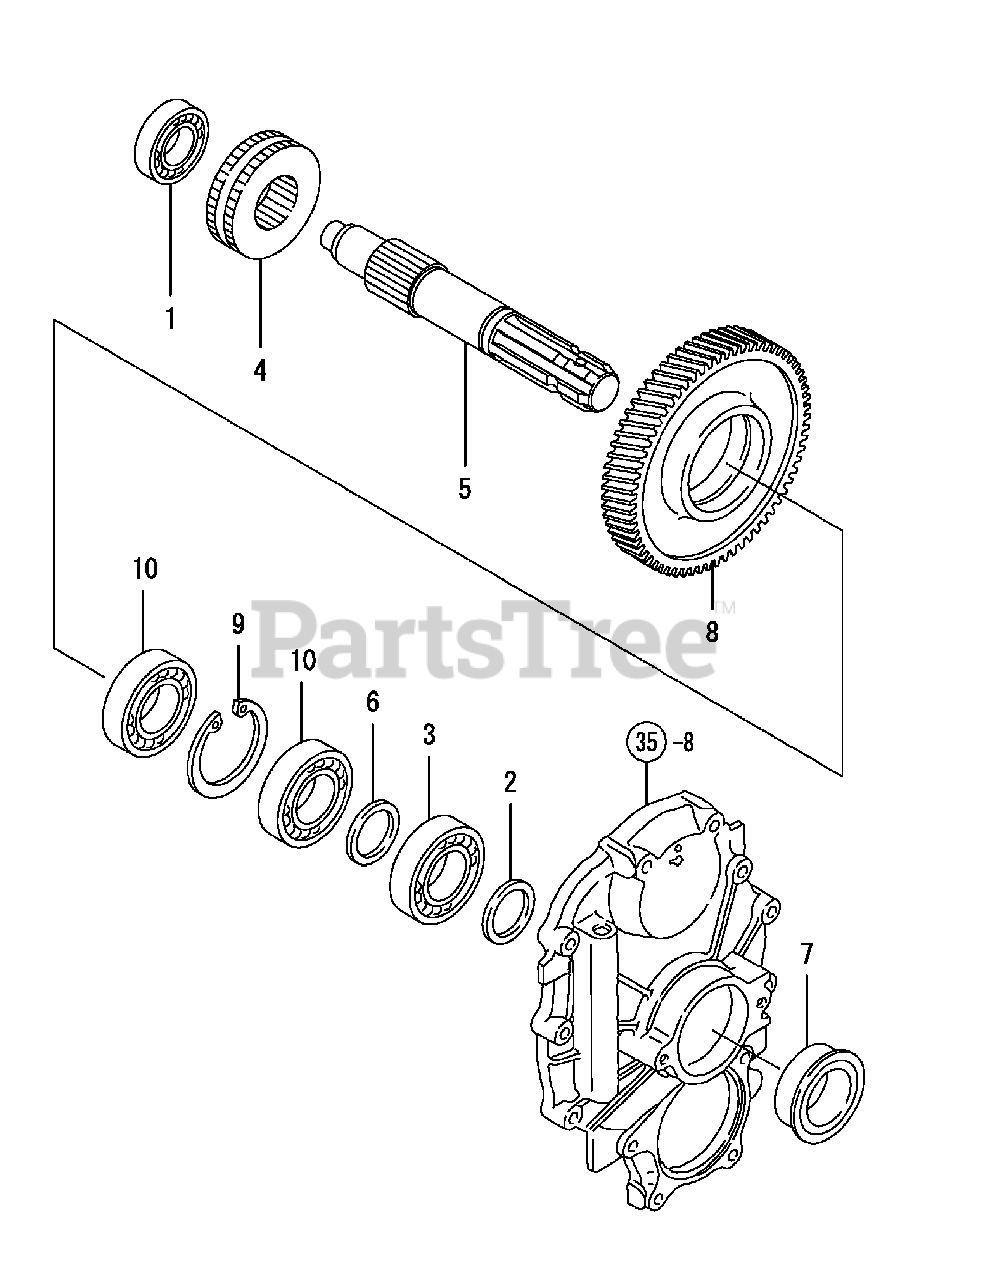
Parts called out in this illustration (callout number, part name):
2	COLLAR 35X45X5
6	WASHER 35X46X32
7	SEAL QLF 35 60 19
